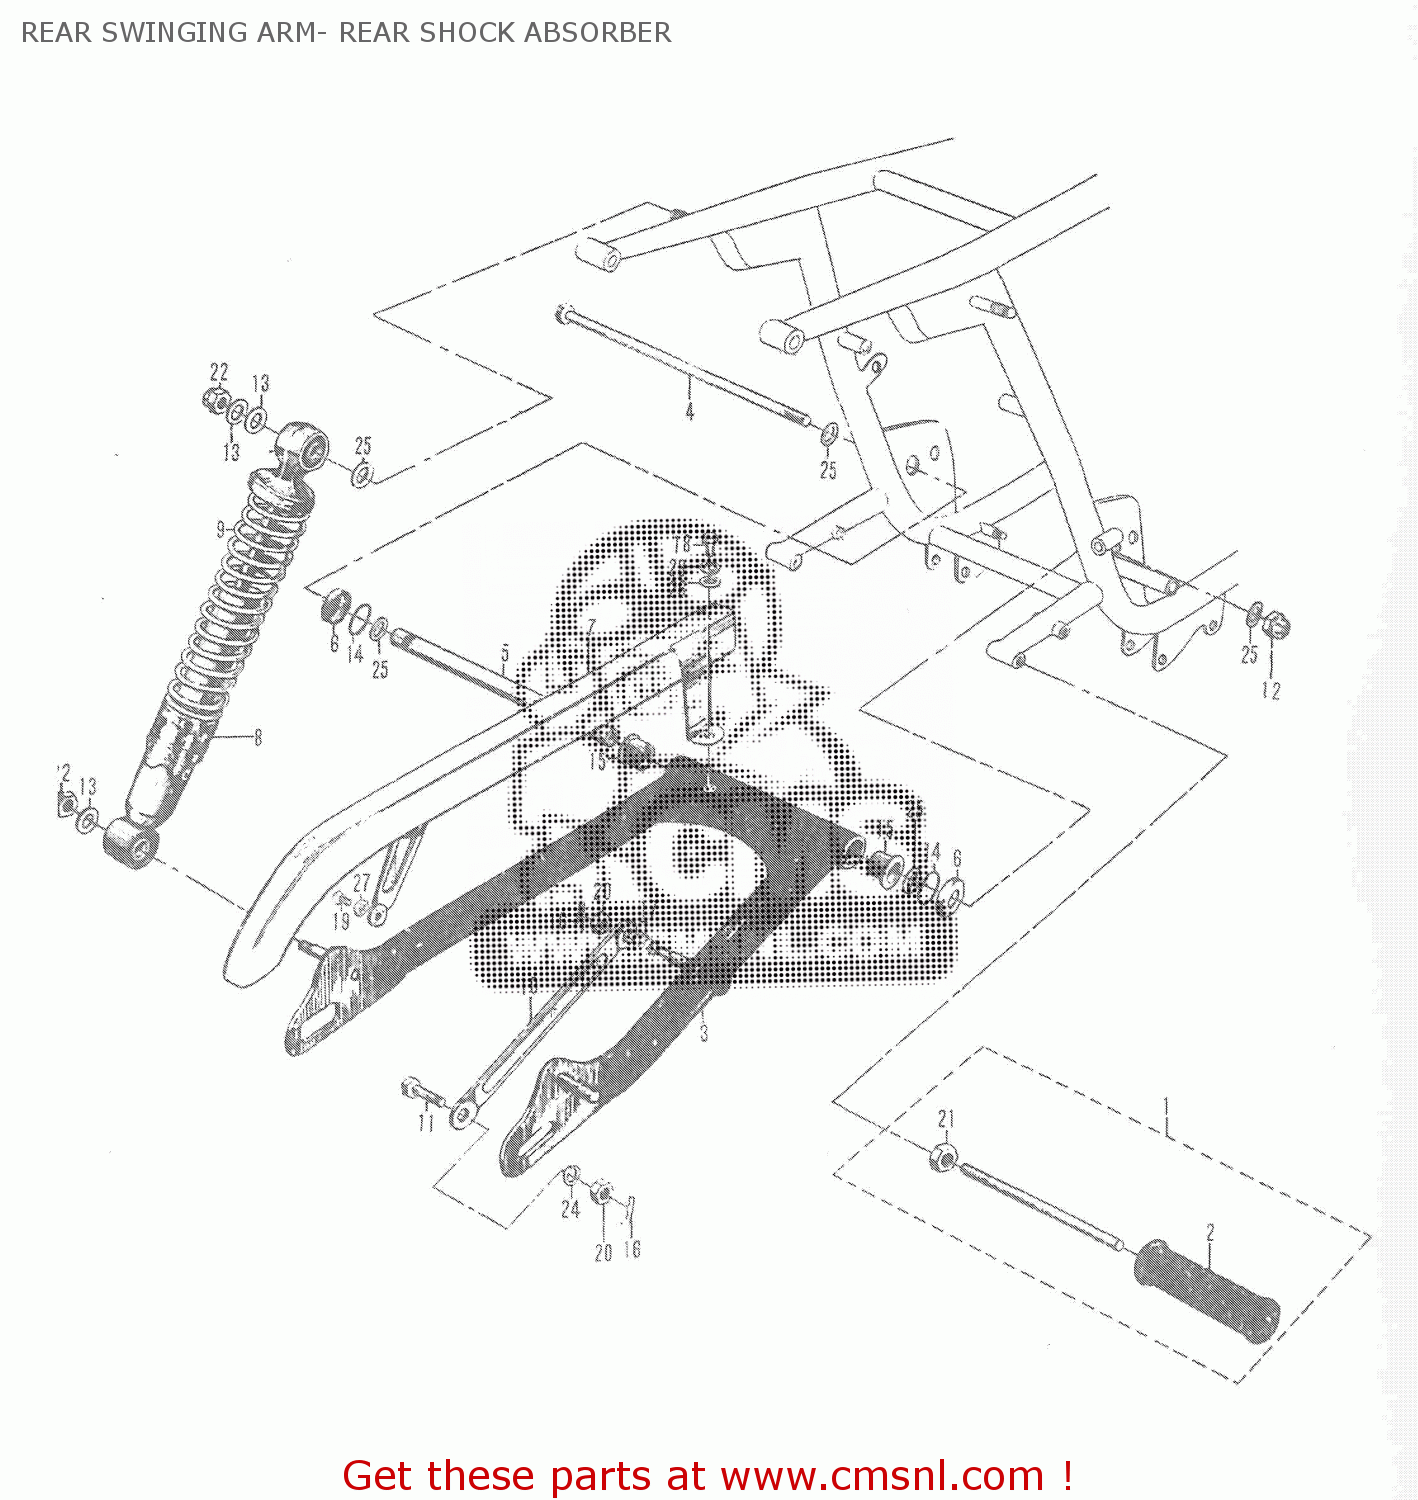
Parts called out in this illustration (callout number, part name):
1	REAR FOOTREST ASS'Y
2	RUBBER,REAR FOOTREST
3	REAR SWINGING ARM
4	REAR SWINGING ARM PIVOT SHAFT
5	REAR SWINGING ARM PIVOT SHAFT SPACER
6	COVER,SWGARM BUSH DUST SEAL
7	CHAIN CASE COMP.
8	ABSORBER ASSEMBLY,REAR SHOCK
9	SPRING
10	TORQUE LINK,REAR
11	BOLT(10X31)
12	REAR SWINGING ARM PIVOT SHAFT NUT
13	WASHER
14	O RING(D:2,ID:24.5)
15	BUSHING
16	CLIP
17	SPRING
18	HEXAGON BOLT
19	CROSS HEAD SCREW
20	HEXAGON NUT
21	SMALL HEXAGON NUT
22	CROWN NUT
23	LOCK WASHER
24	LOCK WASHER
25	SMALL FLAT WASHER
26	FLAT WASHER
27	TOOTHED LOCK WASHER
